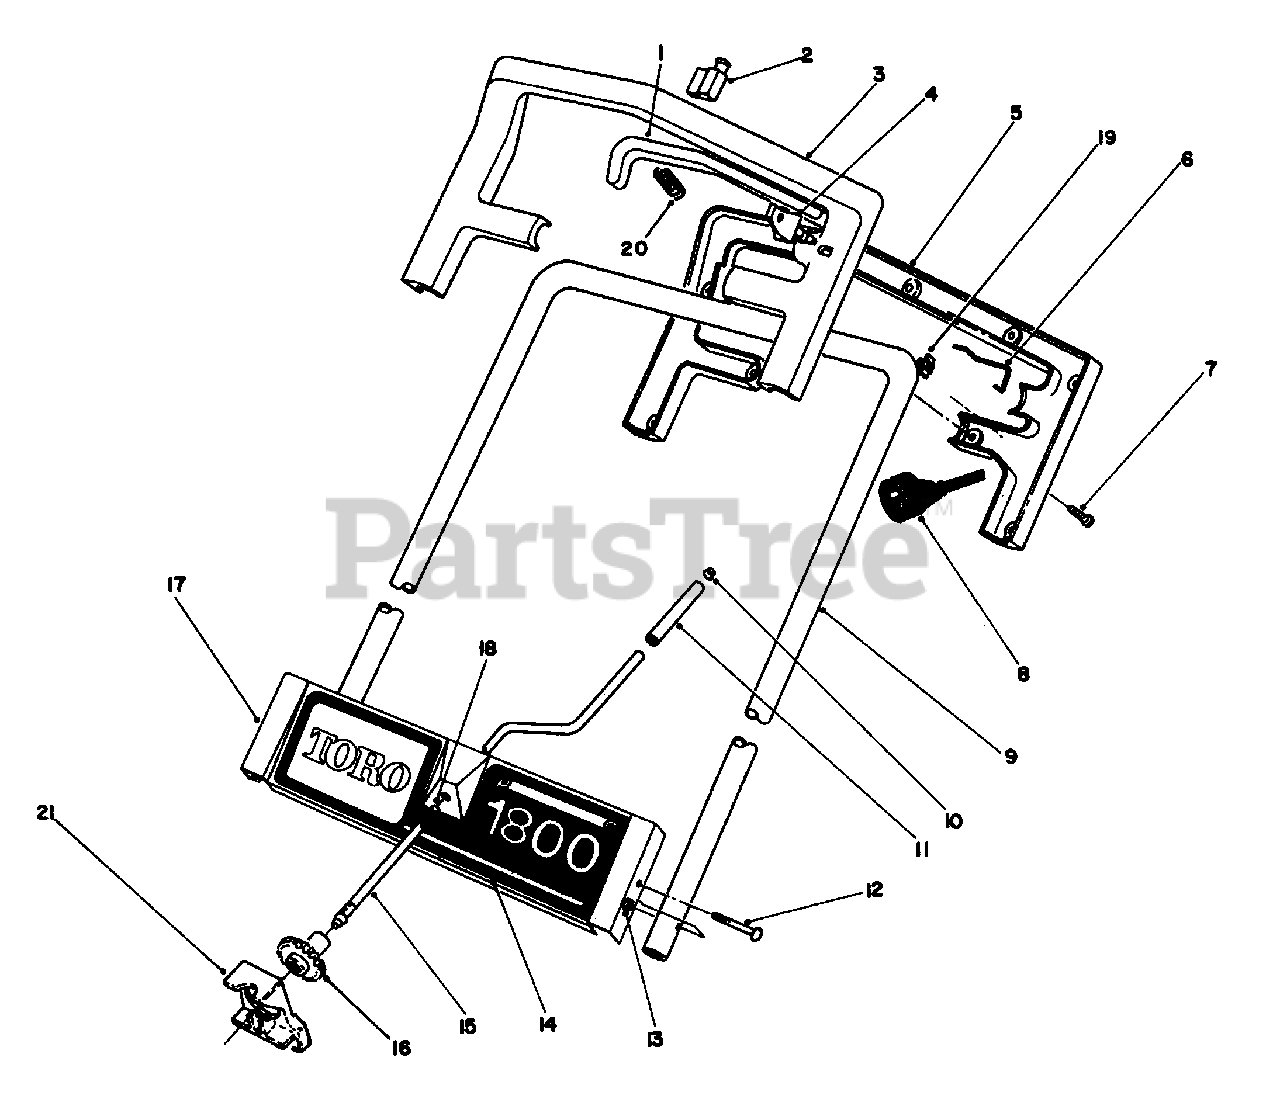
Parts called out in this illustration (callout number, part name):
1	Bar-Switch Used on Machines Serial Nos. (1100101 Thru 1111100 & 1200101 & UP)
2	Switch
3	Handle-Upper Control Used on Machines Serial Nos. (1100101 Thru 1111100 1200101 & UP)
5	Handle-Lower Control Used on Machines Serial Nos. (1100101 THRU 1111100 & 1200101 & UP)
6	Spring-Lock Used on Machines Serial Nos. (1000101 Thru 1011100)
7	Screw-Pan Hd. Form.
8	Cord-Supply Used on Machines Serial Nos. (1100101 Thru 1111100 & 1200101 & UP )
9	Tube-Upper Handle Used on Machines Serial Nos. (1100101 Thru 1111100 & 1200101 & UP )
10	Push Nut
11	Sleeve-Chute Crank
12	Screw-Hex. Hd. Mach.
13	Nut-Lock
14	Decal-Escutcheon
15	Rod-Chute Crank
16	Gear-Chute Crank
17	Plate-Escutcheon
18	Bushing-Snap In
19	Lock-Slider Used on Machines Serial Nos. (1100101 Thru 1111100 & 1200101 & UP)
20	Spring Used on Machines Serial Nos. (1100101 Thru 1111100 & 1200101 & UP)
21	Brake-Gear
